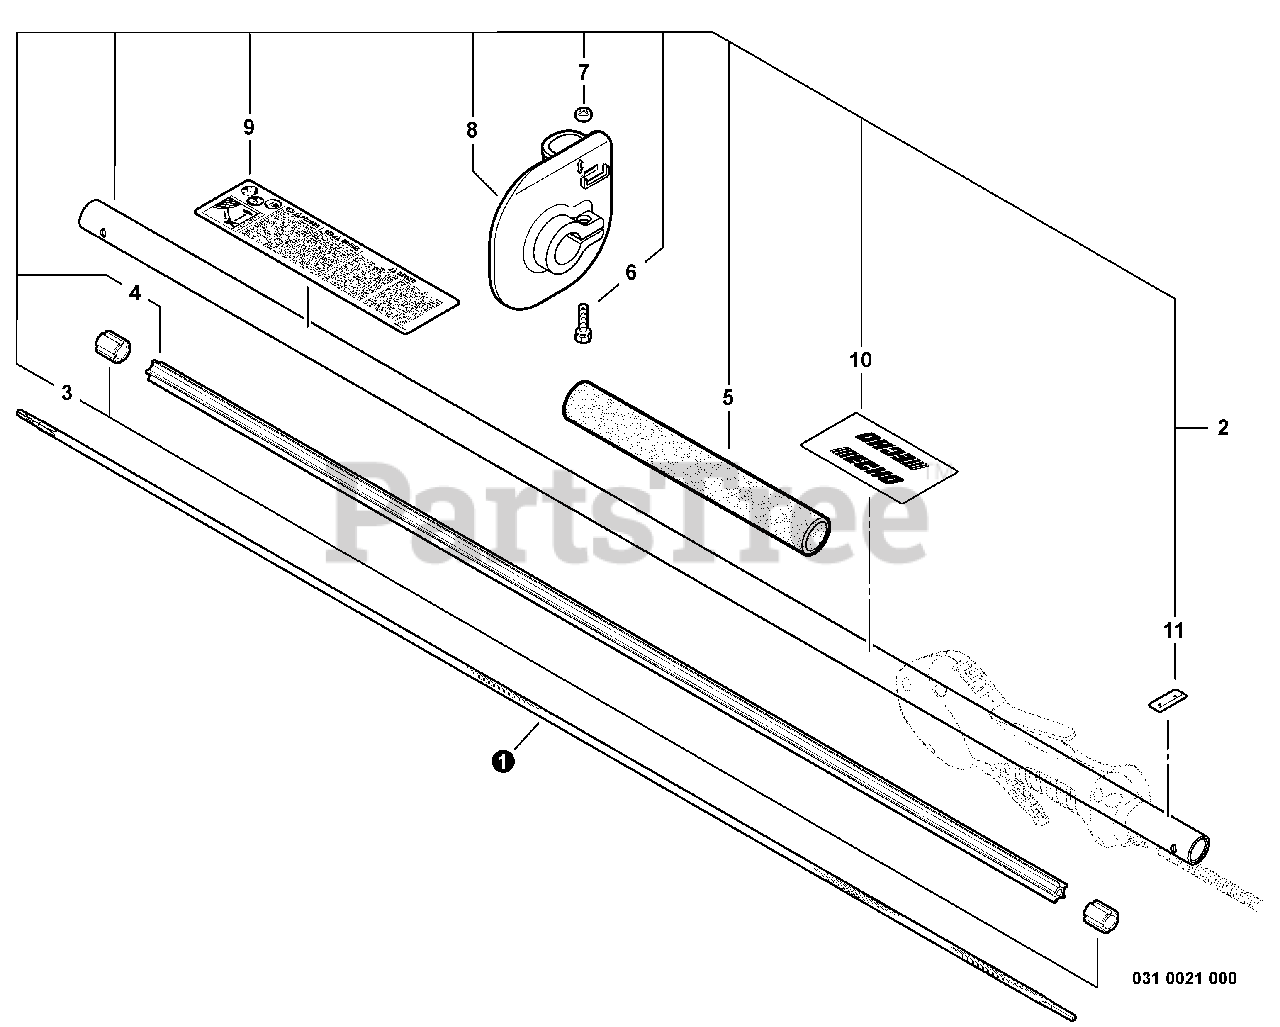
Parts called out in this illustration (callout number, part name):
1	DRIVESHAFT - FLEXIBLE
2	MAIN PIPE ASSY
4	LINER - FLEXIBLE
5	GRIP, HANDLE
6	BOLT - 5X20
8	GUARD
9	LABEL - CAUTION
10	LABEL - HANDLE LOCATION
11	LABEL - ALIGNMENT
